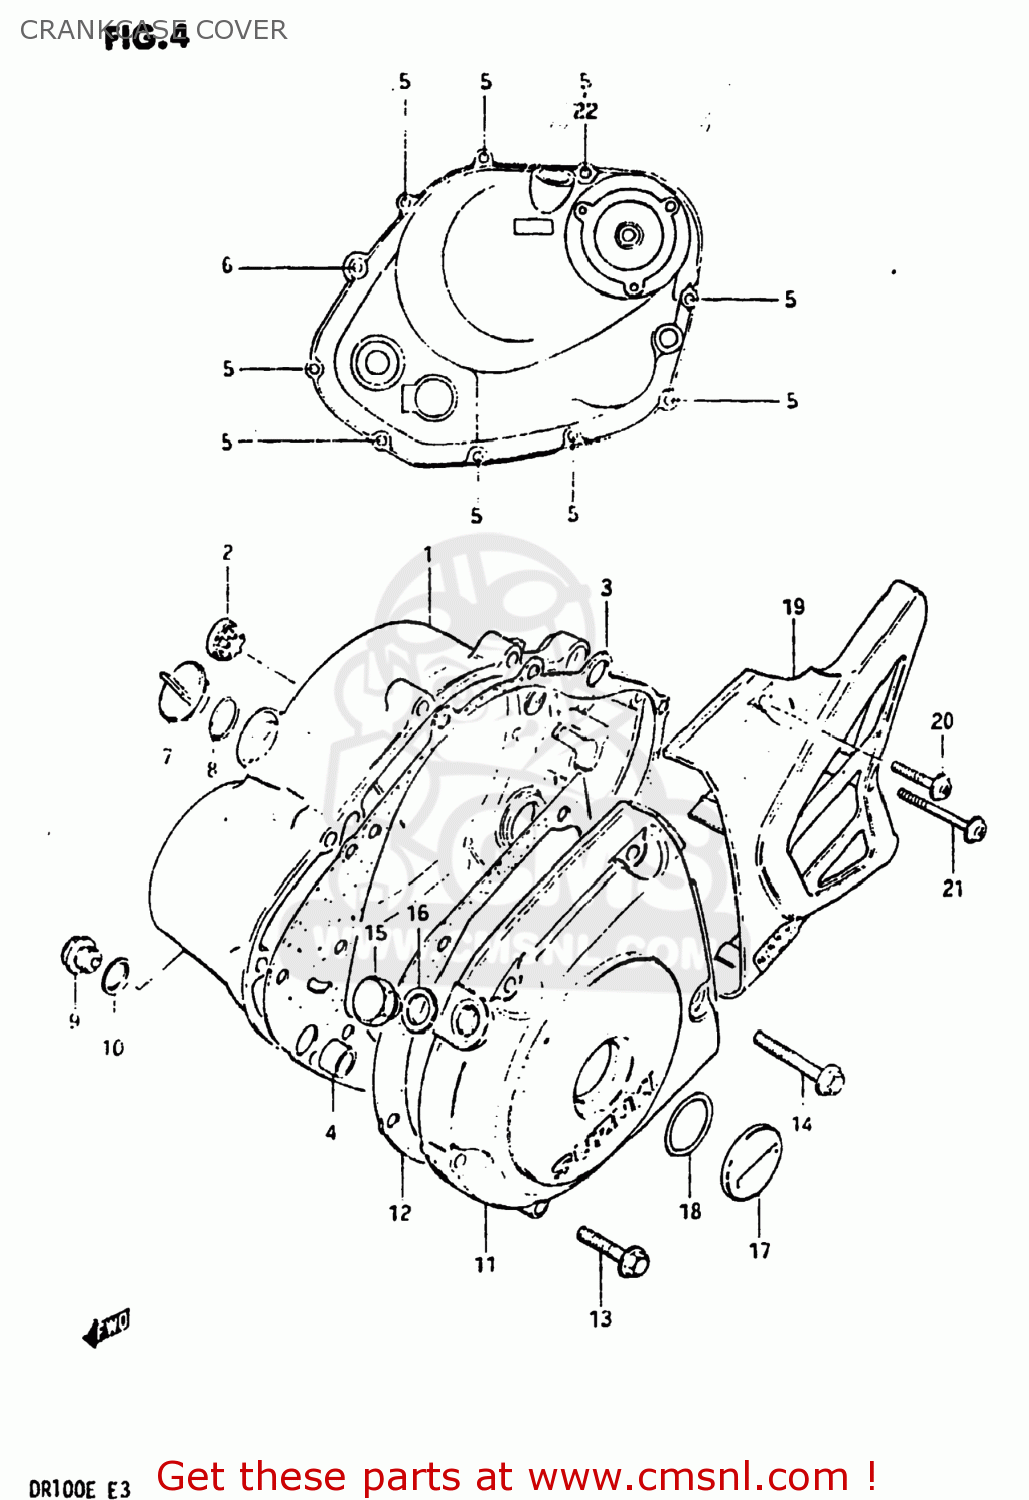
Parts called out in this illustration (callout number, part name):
1	COVER,CLUTCH
2	LENS,OIL LEVEL CHECK
3	GASKET,CLUTCH COVER (MCA)
4	PIN
5	BOLT (6*30)
6	BOLT (6X45)
7	PLUG
8	O RING(D:3.1,ID:16.8)
9	PLUG(14X12)
10	GASKET(14X19.2X2) (NAS)
11	COVER,MAGNETO
12	GASKET,MAGNETO COVER (MCA)
13	BOLT (6*30)
14	BOLT (6X40)
15	PLUG(12X9)
16	GASKET(12.1X16.2X3.7) (NAS)
17	PLUG
18	O RING(D:3.1,ID:22.7)
19	COVER,SPROCKET
20	SCREW
21	SCREW
22	WASHER
